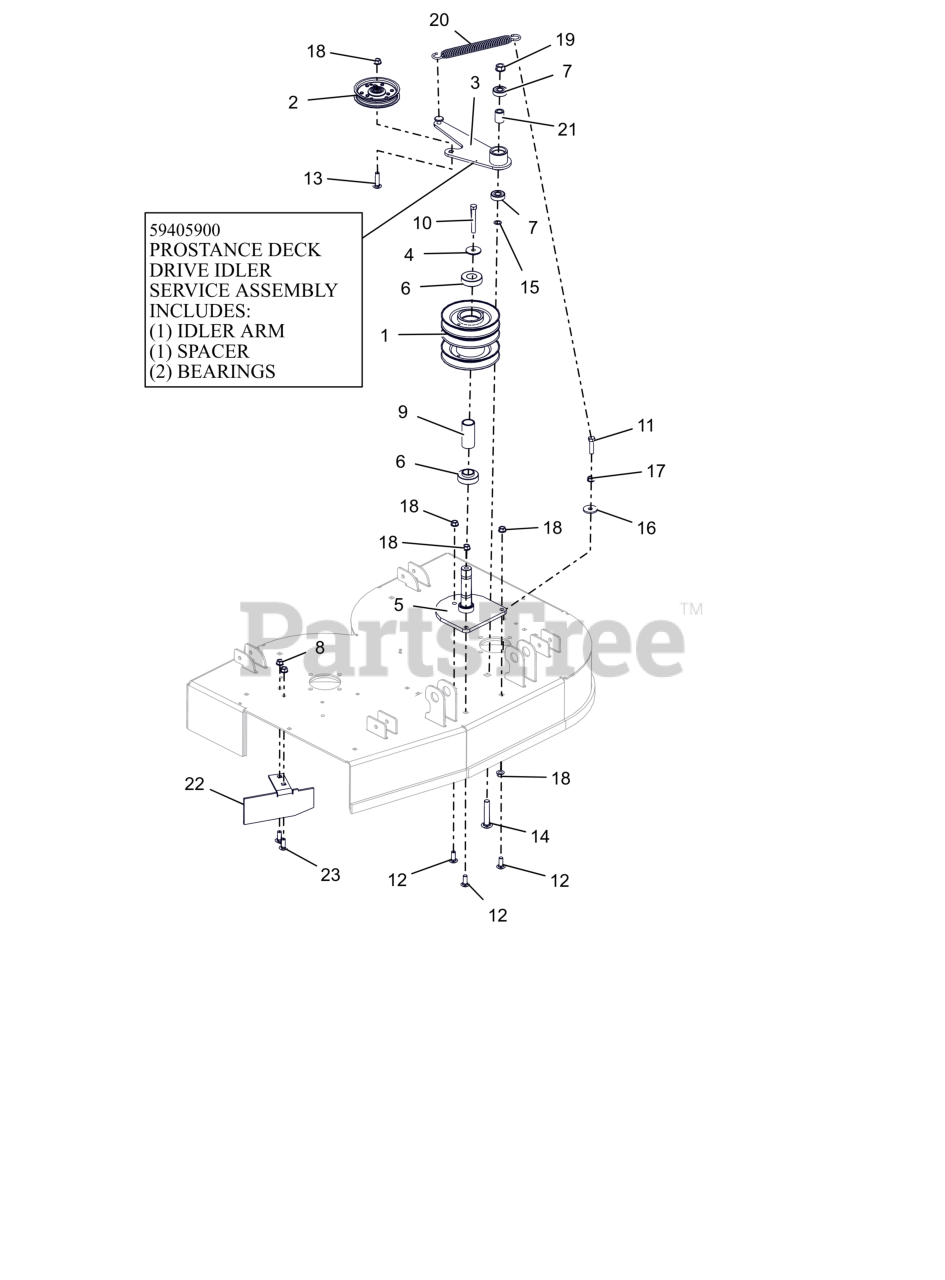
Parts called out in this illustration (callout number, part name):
1	WLDMT, JACKSHAFT HOUSING
2	ASM, 4" IDLER (.75 WIDE)
3	WLDMT, DECK IDLER ARM
4	RETAINER, JACKSHAFT SPINDLE
5	WLDMT, JACKSHAFT BASE (BLACK)
6	BEARING, RG 1.000 X 2.0467 X .591
7	BRG-BALL .500X1.38X.437
8	NUT-LK-CTR-FLG .375-16 GF ZCC
9	SPCR, SLV 1.010 X 1.250 X 2.661
10	BLT, HEX .38-16X2.75 G8 ZCC
11	BLT, HEX 0.375-16X1.5 GR8 ZCC
12	BLT,RHSSN .38-16X1.00 G5 ZCC
13	BLT, RHSSN .38-16X1.50 G5 ZCC
14	BTL,RHSSN .500-13 X 3.25 G5 ZCC
15	WASHER, .500X.750X.020 THRUST
16	WSHR,FLT .406X1.375X.135 ZCC
17	NUT, SPNLK-FLG .38-16 G5 ZCC
18	NUT-LK-CTR-FLG .375-16 GF ZCC
19	NUT-LK-CTR-FLG .500-13 GG ZCC
20	SPRING, EXTENSION
21	SPACER .510 X .75 X 1.1485
22	BAFFLE, 36" SIDE DISCHARGE (RED)
23	BLT,RHSSN .38-16X1.00 G5 ZCC
